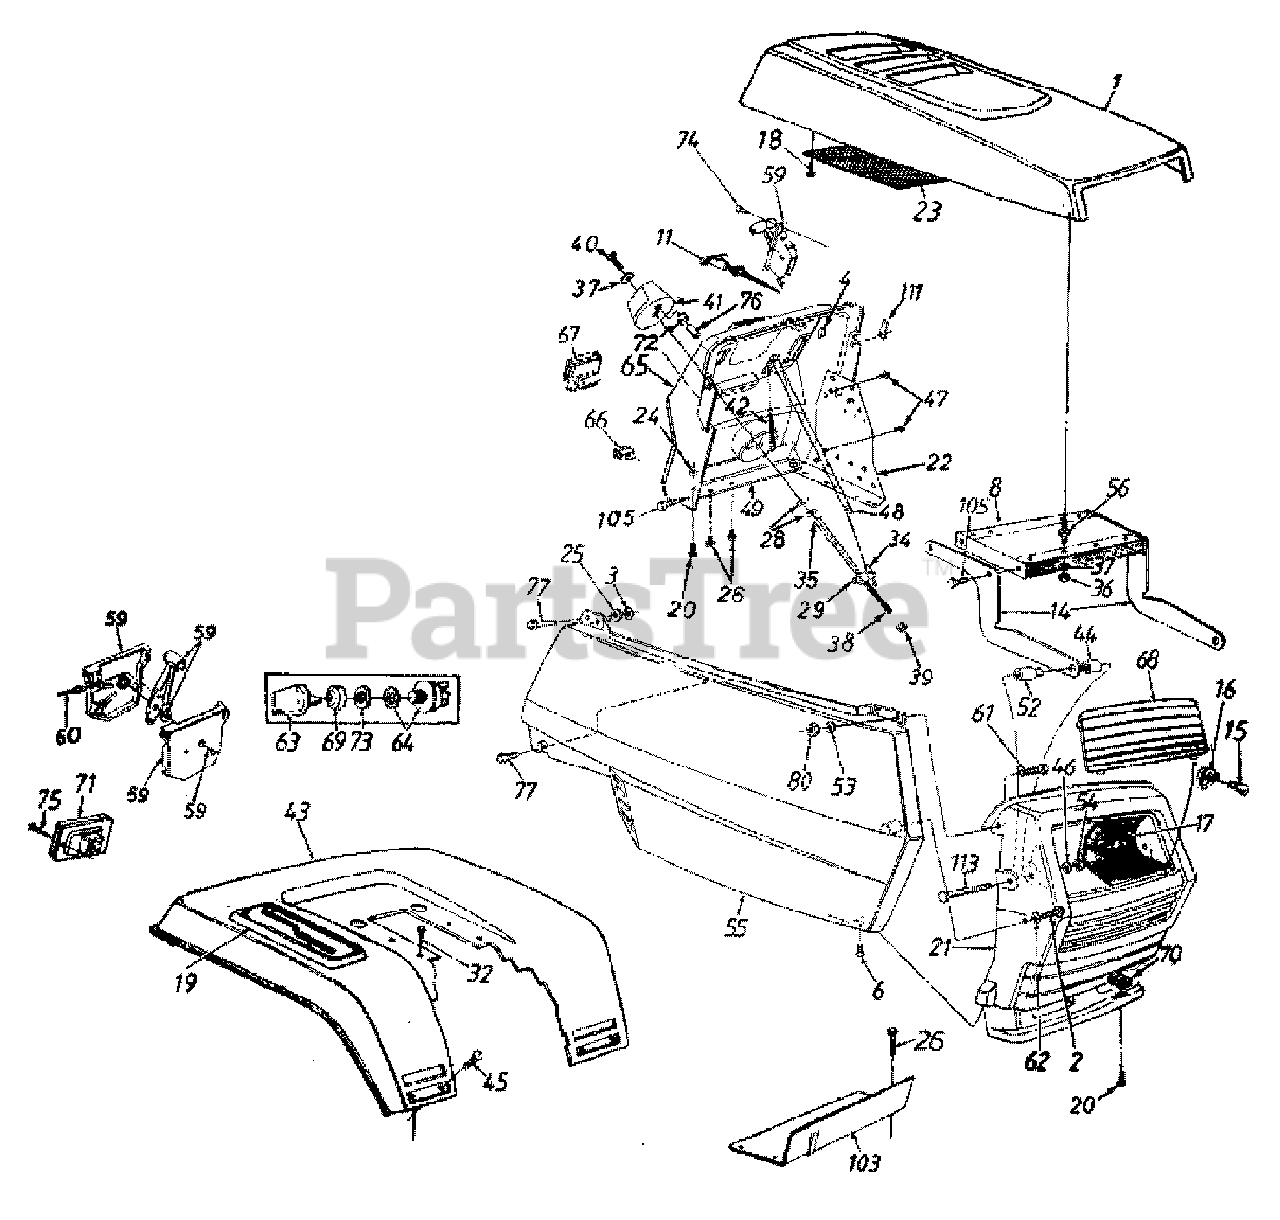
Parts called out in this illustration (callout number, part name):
1	Hood
2	Hex Wash. B-Tap Scr.1/4 x .62" Lg.
3	Bolt Retainer 1/4" I.D.
4	Retainer Clip
6	Truss Mach. B-Tap Scr.#10 x .5" Lg.
16	Twist Lock-Lamp Socket
17	Reflector-Headlight
18	Hex Wash. Hd. AB-Tap Scr.#8 x .5" Lg.
19	Speed Selector Plate
20	Hex Bolt 5/16-18 x .75" Lg.
21	Grille
24	Hex Sems Nut 5/16-18 Thd.
25	Fl-Wash. 1/4" I.D. x .93" O.D.
26	Hex Wash. Hd. B-Tap Scr. 5/16-18 x .5" Lg.
28	Fl-Wash. 3/8" I.D. x .875" O.D.
29	Adj. Ferrule 3/8-8 Thd.
34	Hairpin Clip
35	"E"-Ring .375" Dia.
36	Hex Nut 1/4-20 Thd.
37	Bell-Wash. .265" I.D. x .75"
38	Adjustment Rod
39	Hex Nut 3/8-8 Twin Thd.
40	Hex Bolt 1/4-20 x .75" Lg.
41	Plastic Knob
42	Ext. Spring 3.21" Lg.
45	Carriage Bolt 1/4-20 x .50" Lg.
46	Fl-Wash. .328" I.D. x .68" O.D.
47	Hex Wash. Hd. Scr. 1/4-20 x .5" Lg.
48	Indicator Strip
53	Fl-Wash. .281" I.D. x .5" O.D.
54	Hex Cent. L-Nut 5/16-18 Thd.
55	Side Cover-R.H.
56	Double Ended Stud 1/4-20 Thd.
59	Throttle Control Box Ass'y.
60	Throttle Control Wire 35" Lg.
61	Hex Bolt 1/4-20 x .62" Lg.
62	Fl-Wash. .281" I.D. x .73" O.D.
64	Ignition Switch
65	Dash Panel
66	Light Switch
67	Ammeter
68	Lens
69	Ignition Switch Cap
70	U-Nut 5/16-18 Thd.
71	Taillight
73	Ignition Switch Nut
74	Truss Mach. AB-Tap Scr.#10 x .5" Lg.
75	Truss Hd. AB-Tap Scr. #6 x .62" Lg.
76	Ball Plunger
77	Hex Wash. Hd. Tap Scr.1/4 x .75" Lg.
80	Hex L-Nut 1/4-20 Thd.
111	Speed Nut 1/4-20 Thd.
113	Hex Bolt 5/16-18 x 2.75"
